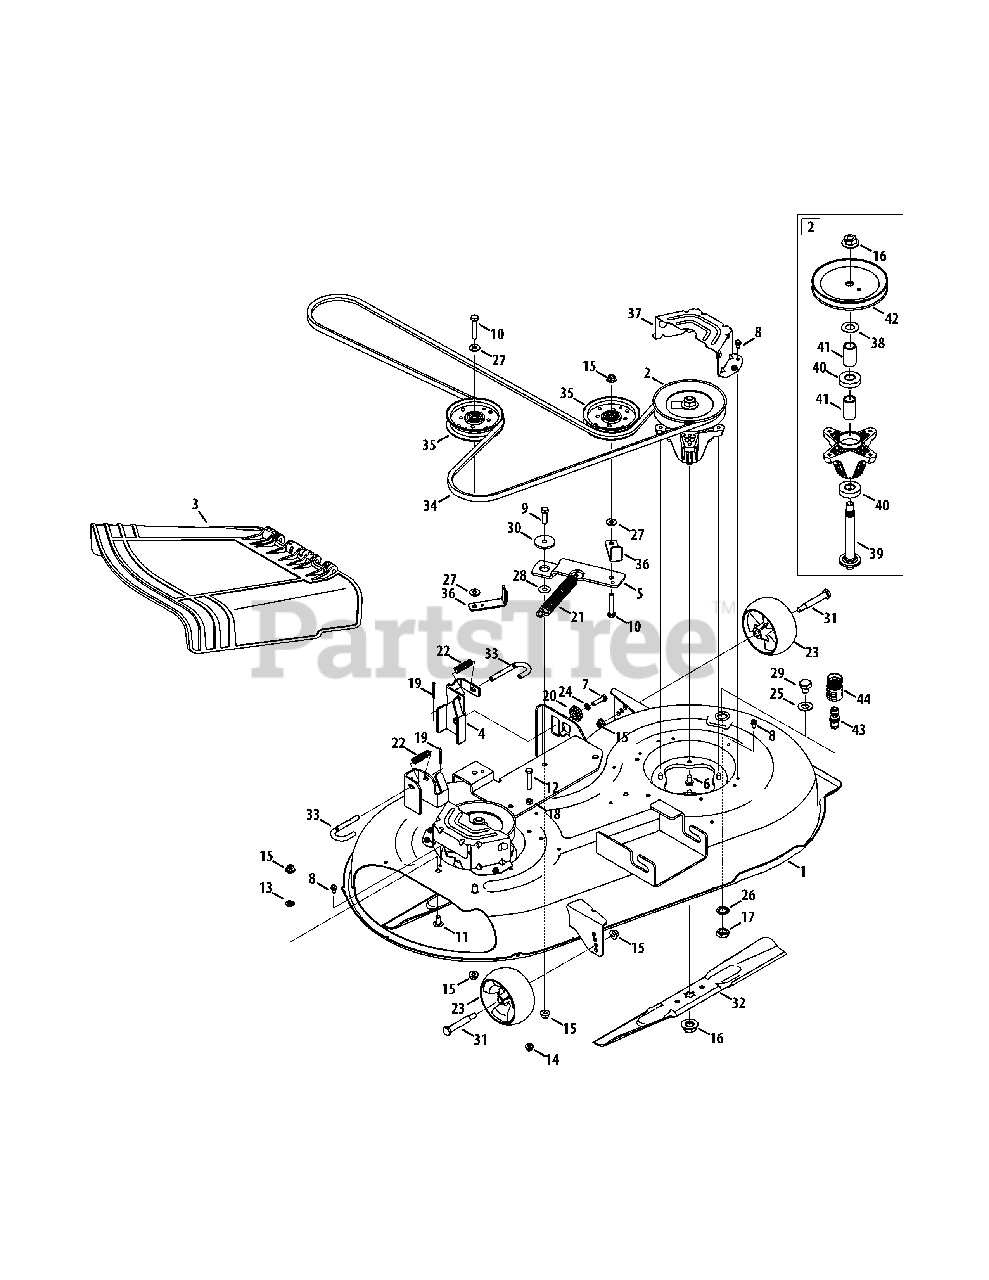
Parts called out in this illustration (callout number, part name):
1	Deck Housing
2	Spindle Assembly
3	Discharge Chute Assembly
4	Deck Lift Bracket
5	Pivot Idler Bracket
6	Hex Washer Head Screw, 5/16-18 x .750
7	Hex Cap Screw, 5/16-18 x 1.25
8	Hex Washer Head Screw, 1/4-20 x .5
9	Hex Cap Screw, 3/8-16 x 1.25
10	Hex Cap Screw, 3/8-16 x 2.00
11	Carriage Screw, 3/8-16 x .75
12	Hex Cap Screw, 5/16-18 x 1.75
13	Push Nut, 3/8
14	Flange Lock Nut, 5/16-18
15	Flange Lock Nut, 3/8-16
16	Hex Flange Nut, 5/8-18
17	Hex Nut, M16-1.5
18	Hex Nut, 5/8-18
19	Cotter Pin, 1/8 x 1.25
20	Deck Adjustment Gear
21	Extension Spring, .94 Dia. x 6.74
22	Compression Spring, .535 x 1.751
23	Deck Ball Wheel, 5.0
24	Lock Washer, 5/16
25	Flat Washer, .64 x 1.24 x .06
26	Internal Tooth Lock Washer, 5/8
27	Flat Washer, .385 x .870 x .092
28	Flat Washer, .385 x 1.00 x .030
29	Bolt, M16 x 1.5
30	Shoulder Spacer, .884 x .190
31	Shoulder Screw, .5 x 2.5 x 3/8-16
32	Blade, 2 in 1, 21.23
33	Deck Hanger Rod
34	V-Belt
35	Idler Pulley, 4.25 Dia.
36	Bracket, Belt Guard
37	Belt Cover
38	Washer, .760 x 1.50 x .030
39	Spindle Shaft
40	Ball Bearing
41	Spacer, .792 x 1.060 x 1.860
42	Deck Pulley
43	Deck Water Nozzle
44	Water Nozzle Adapter
